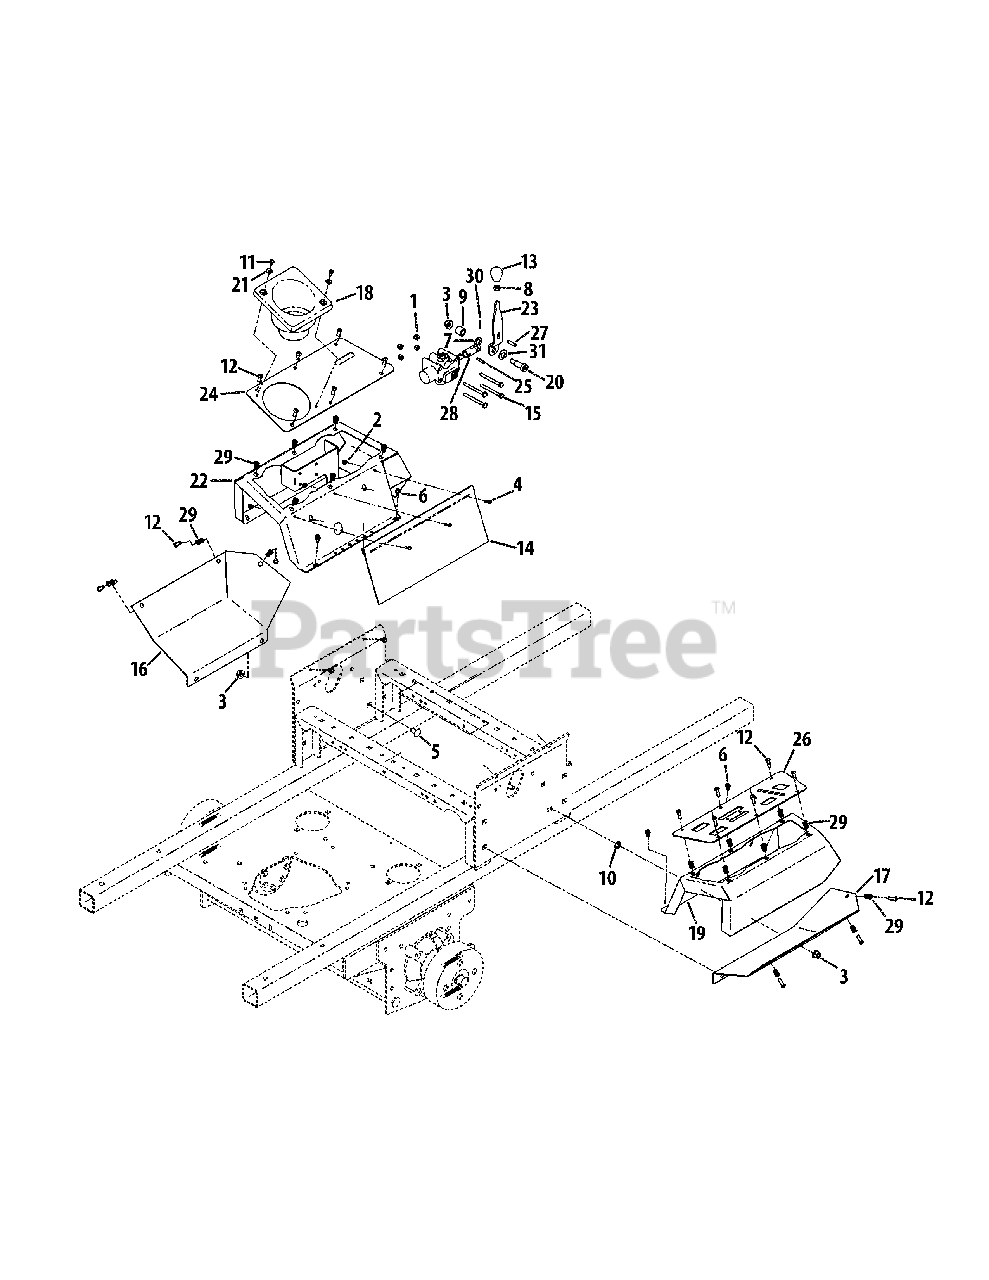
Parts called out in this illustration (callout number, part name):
1	Nylock Nut, 1/4-20
2	Nylock Nut, #10-32
3	Flange Counter Lock Nut, 3/8-16
4	Machine Screw, #10-32 x .625
5	Carriage Bolt, 3/8-16 x .75
6	Hex Flange Screw, 1/4-20 x .500
7	Washer, .536 x .930 x .050
8	Jam Nut, 3/8-16
9	Spacer, .500 x .750 x .700
10	Push Nut, .335 x .780 x .015
11	Flange Screw, #10-32 x .500
12	Screw, 1/4-20 x .750
13	Lever Knob, 3/8-16
14	Debris/Storage Bag
15	Hex Screw, 1/4-20 x 2.75
16	LH Lower Panel
17	RH Lower Panel
18	Cup Holder
19	RH Control Panel
20	Shoulder Bolt, 3/8-16 x .50 x 1.0
21	Washer, .300 x .550 x .047
22	LH Control Assembly
23	Lift Valve Lever Bracket
24	LH Cover Control Panel
25	Spirol Pin, 3/16 x 1.0
26	RH Cover Control Panel
27	Pin, .25 x .9375
28	Valve Link
29	Rivet Nut, 1/4-20
30	Cotter Pin, 1/16 x .75
31	Bell Washer, .525 x 1.00 x .050
